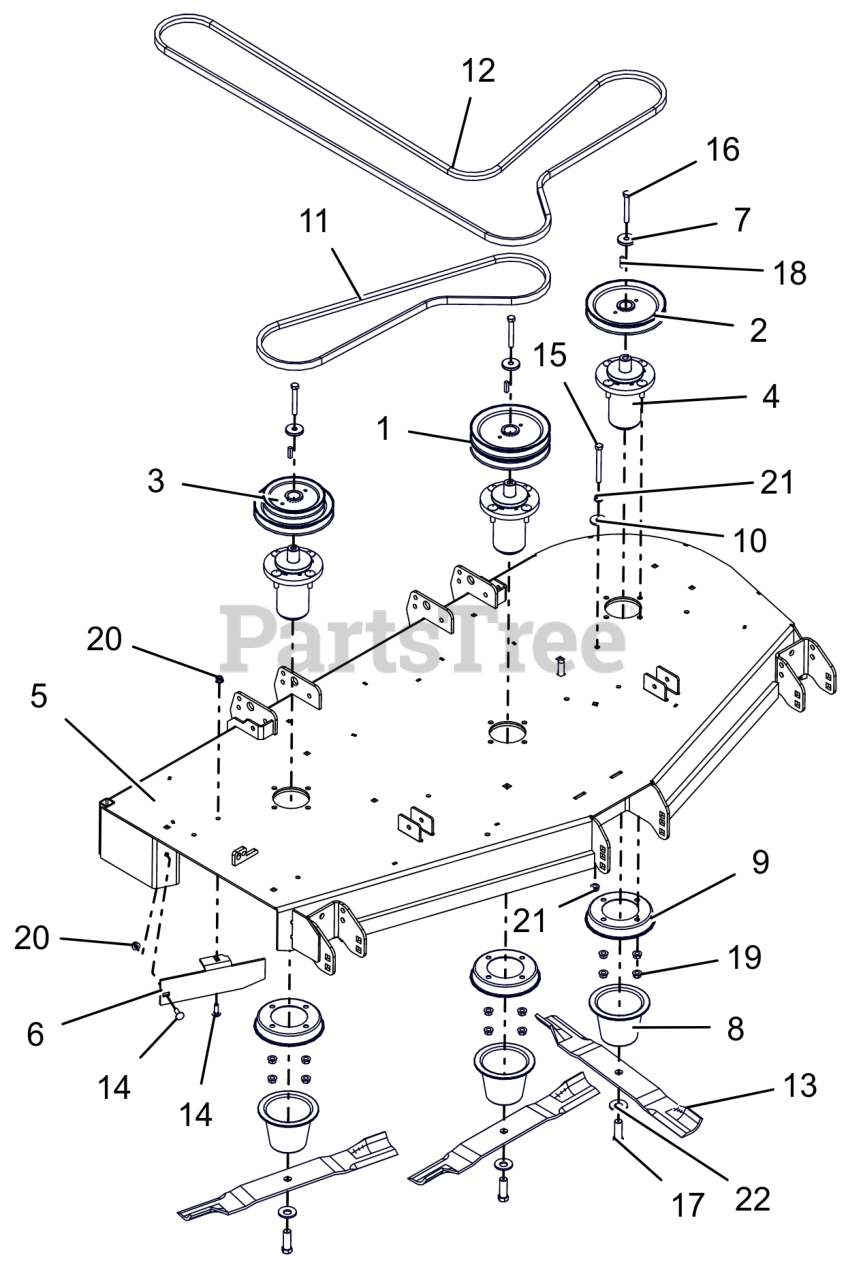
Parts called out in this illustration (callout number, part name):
1	PULLEY, DOUBLE-1"ID X 6.75"OD
2	PULLEY, V-1" ID X 6.75" OD
3	PULLEY, DBL-1"IDX6.75"&5.25"OD
4	ASM, MAINT FREE ALUM SPINDLE
5	DECK, PT160 W/SAFETY DECALS
6	60" DISCHARGE BAFFLE - RED
7	RETAINER, SHEAVE
8	GUARD, SPINDLE LOWER
9	GUARD, SPINDLE TOP
10	WSHR,FLT .406X1.375X.135 ZCC
11	V-BELT, B-COGGED
12	BELT, B-SECTION EPDM RAW EDGE
13	BLADE, MOWER (20.50")
14	BLT,RHSN .31-18X1.00 G5 ZCC
15	BLT, HEX .38-16X3.50 G5 ZCC
16	BLT, HEX .38-16X2.75 G8 ZCC
17	BLT, HEX .62-18X1.75 G8 ZCC
18	KEY, SQ .25X.25X1.00 RC 40-50
19	NUT-LK-CTR-FLG .375-16 GF ZCC
20	NUT,NYL-FLG .31-18 GF ZCC
21	NUT, SPNLK-FLG .38-16 G5 ZCC
22	WSHR-BLVL .669X1.535X.138
